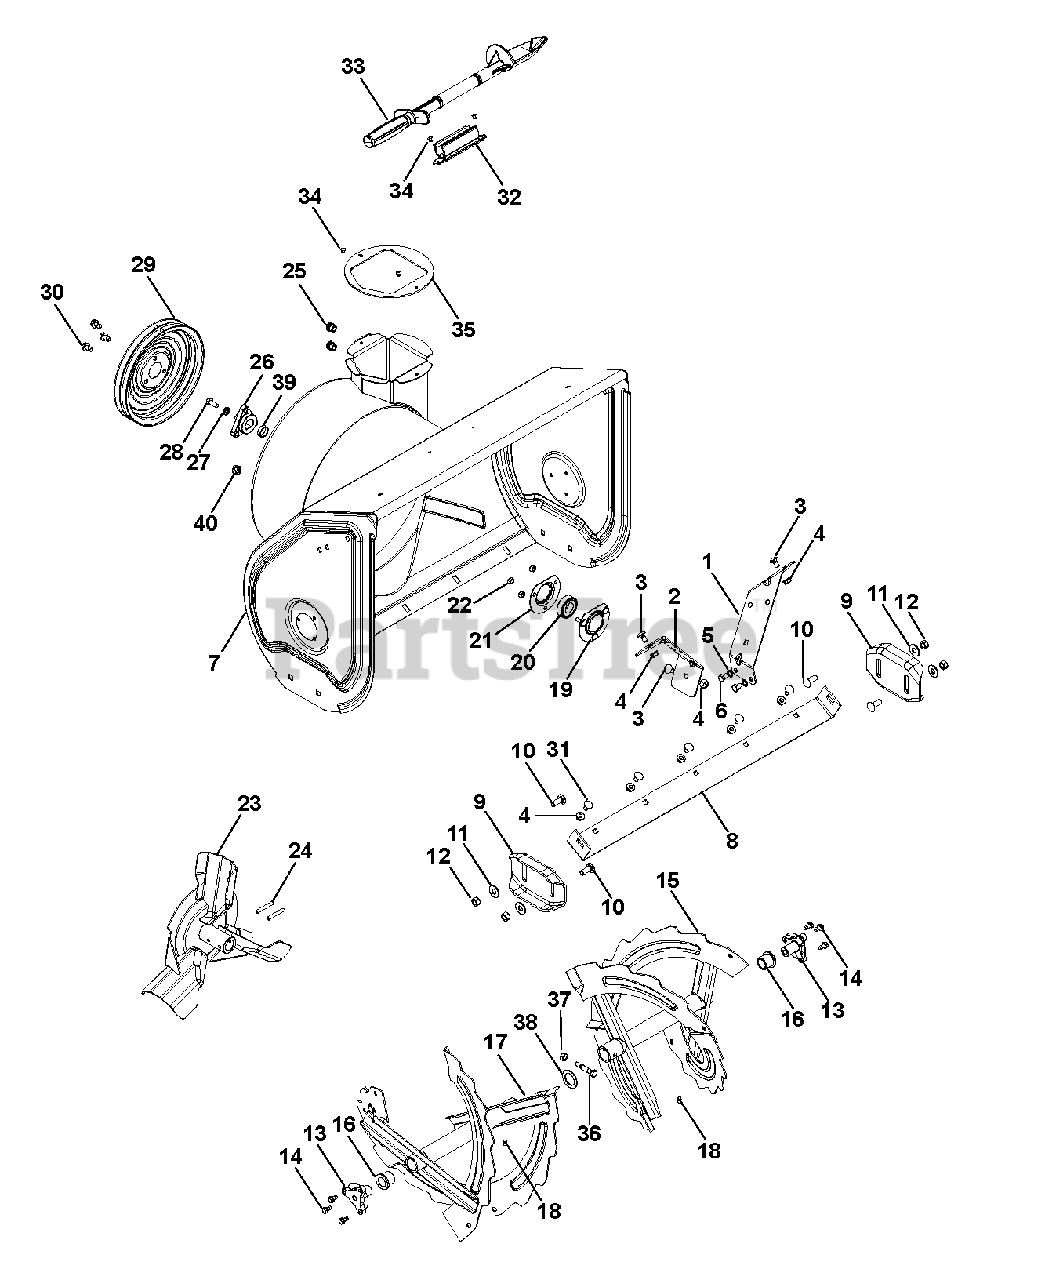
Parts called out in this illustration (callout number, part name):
1	BRACKET, GEARCASE SUPPORT - LH
2	BRACKET, GEARCASE SUPPORT - RH
3	BLT-RDHDSQSHNK.31-18X.62 YZ-LK
4	@NUT-LK-TOP-FLG .31-18 YWZC
5	@WSHR-LK-EXT.326X.599X.031YWZC
6	@BLT-HEX .31-18X.50 GR5 YWZC
7	BLOWER HOUSING W/DECAL 30"
7	BLOWER HOUSING, 28"
7	BLOWER HOUSING W/DECAL 24"
8	BLADE, SCRAPER-30"
8	BLADE, SCRAPER - 28"
8	BLADE, SCRAPER-24"
9	SKID SHOE, REVERSIBLE - ORANGE
10	@BLT-RDHDSHSQNK.38-16X1.0 G5YZ
11	@WSHR-FL-STL.438X1.00X.083 YWZ
12	@NUT-LK-CTR .38-16 YWZC
13	SUPPORT, RAKE BUSHING
14	SCR-TAP .25-20X.50 HWH TR YWZ
15	RAKE, LH W/ZERK - 30"
15	RAKE, LH W/ZERK - 28"
15	RAKE, LH W/ZERK - 24"
16	BSHG-FLG, NY.778 ID X 1.018 OD
17	RAKE, RH W/ZERK - 30"
17	RAKE, RH W/ZERK - 28"
17	RAKE, RH W/ZERK - 24"
18	ZERK,FITTING .25X.125 DRIVE IN
19	BEARING FLANGE
20	BRG-BALL .876 X 1.750 X .50
20	BRG-BALL .876X1.75X.50 RSTFP
21	BEARING FLANGE
22	@NUT-LK-CTR .25-20 YWZC
23	IMPELLER, 3 BLADE-14"
24	PIN-ROLL .250X1.75
25	NUT, THREADED INSERT .38-16
26	PULLEY HUB, D-BORE .87 DELUXE
27	WSHR-LK .312X.097 HVY YWZC
28	BLT-HEX .31-24X.75 YWZC GR5
29	PULLEY, SPIN FORM DUAL GROOVE
30	@SCR-TAP .31-18X.50 HWH TR YWZ
31	BOLT, MODIFIED HEAD CARRIAGE
32	MOUNT, SNOW CLEAN OUT
33	DEVICE, SNOW CLEAN OUT
34	RVT-POP .187 YZ
35	BAFFLE, DISCHARGE NECK
36	SHEAR BOLT SERVICE ASSEMBLY
37	@NUT-LK-CTR .31-18 YWZC
38	WSHR-FL-STL 1.010X1.505X.062YZ
39	BSHG-SPCR .895IDX1.065ODX.353
40	SCR-TAP.31-18X.50 HWH TR YWZ
